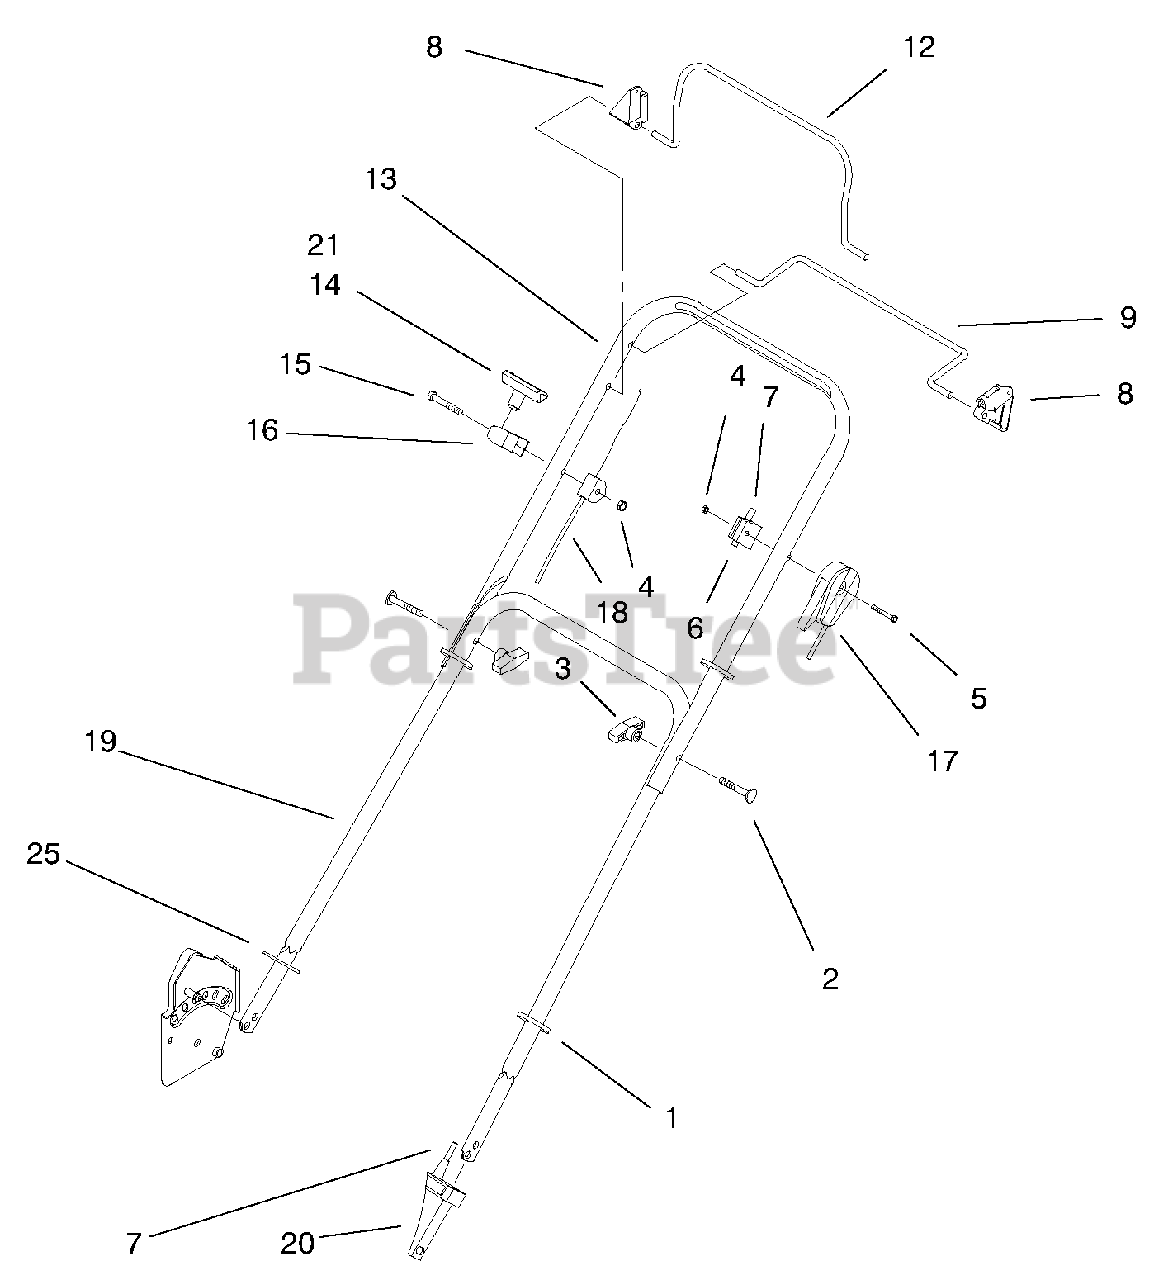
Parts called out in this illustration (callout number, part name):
1	Strap-Tie Sm
3	Knob-Handle
4	Nut-Lock Ni
5	Screw-Hex Hd
6	Anchor-Upper Sp Cable
7	Cable-Traction
8	Stop-Pivot
9	Bail-Sp Control
12	Bail-Brake
13	Handle-Upper
14	Handle-Start Eat
15	Screw-HH
16	Rope-Guide
17	Cable-Throttle
18	Cable-Flywheel Brake
19	Section-Lower Handle
20	Anchor-Cable
21	Starter-Clip Eat
25	Guard-Handle
